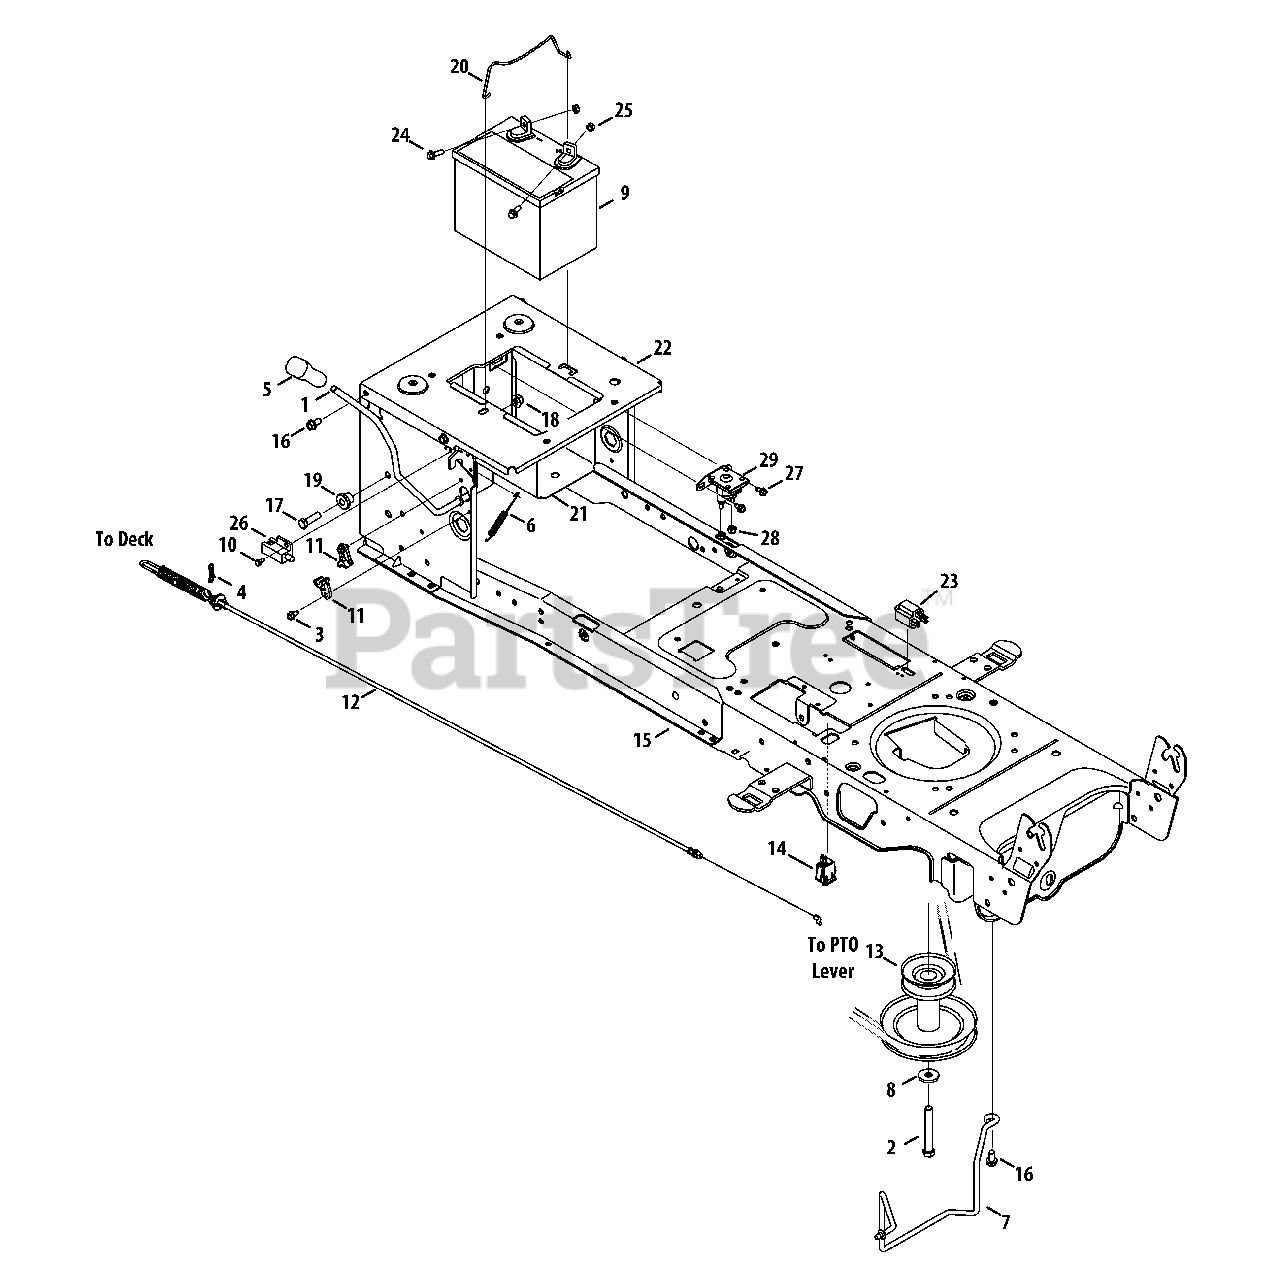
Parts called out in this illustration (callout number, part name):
1	Handle Ass’y, PTO
2	Hex Screw, 7/16-20, 3.50, Gr5
3	Screw, Self-tapping, 1/4-20, 0.50
4	Pin, Cotter, Bow-Tie 72
5	Grip, Handle, Cub
6	Spring, Ext, .38 Dia x 5.6
7	Rod, Keeper
8	Washer, Flat, .450 x 1.250 x .164
10	Screw, Shoulder, #10-32, .500
11	Bearing, PTO
12	Cable, Engag, Deck
13	Pulley, Engine, 3.39 x 6.12 Dia.
14	Switch, Plunger, Snap Mount
15	Frame Ass’y, Lower
16	Screw, Self-tapping, 5/16-18, .750,
17	Hex Screw, 3/8-16, 1.25, Gr5
18	Nut, Flange Lock, 3/8-16, Grf,
19	Spacer, Shoulder, .38 x 1.0 x .70
20	Rod, Battery
21	Tray, Battery
22	Bracket, Frame, Seat
23	Switch, 3-Pole
24	Hex Flange Screw, 1/4-20, .75, Gr5
25	Nut, Sems, 1/4-20
26	Switch, Interlock
27	Screw, Self-tapping, 1/4-20, 0.375,
28	Nut, Flange Lock, 1/4-20, Grf,
29	Solenoid, 12V, 100 Amp, 4 term
